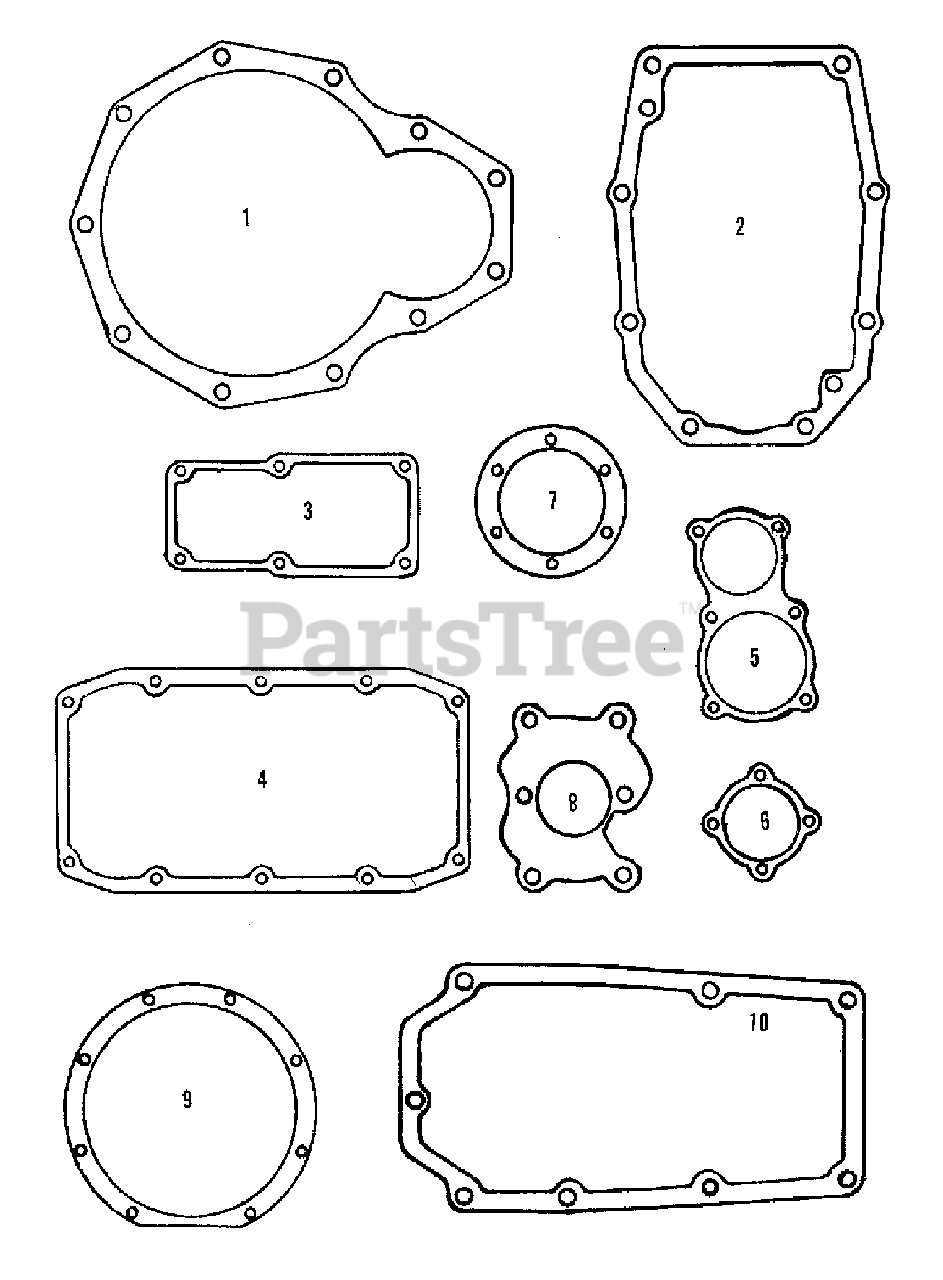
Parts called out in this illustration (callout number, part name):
1	GASKET, sleeve
2	GASKET, rear housing front
3	GASKET, control cover
4	GASKET, shift cover
5	GASKET, front cover
6	GASKET, PTO bearing cover
7	GASKET, bearing retainer, PTO extension
8	GASKET, brake plate
9	GASKET, brake cover
